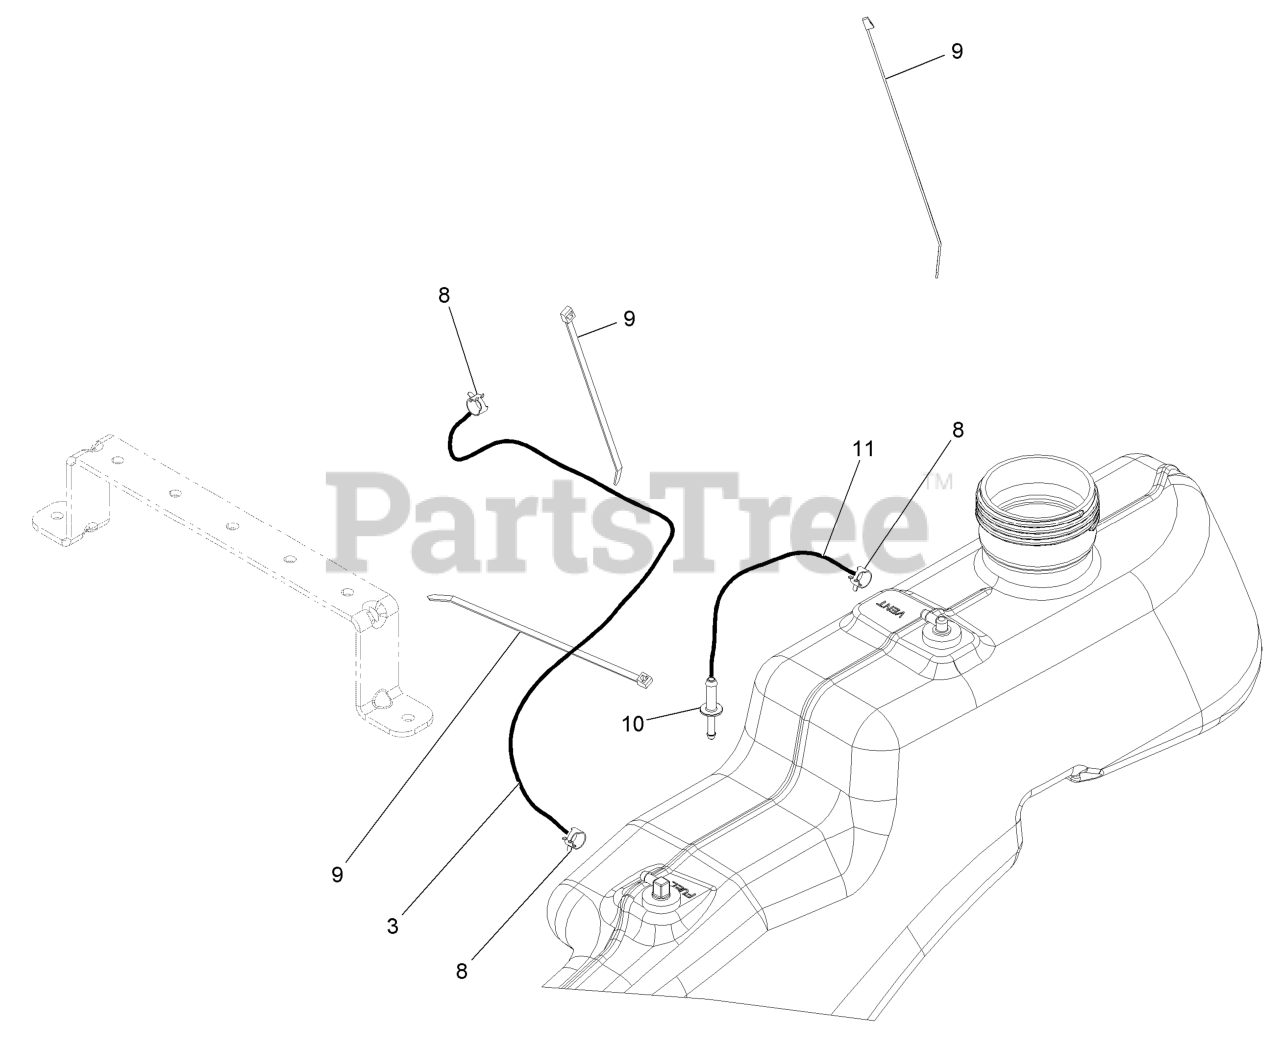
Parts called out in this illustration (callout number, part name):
3	HOSE-FUEL
8	CLAMP-HOSE
9	TIE-CABLE
10	ADAPTOR-ORIFICE
11	HOSE-FUEL
